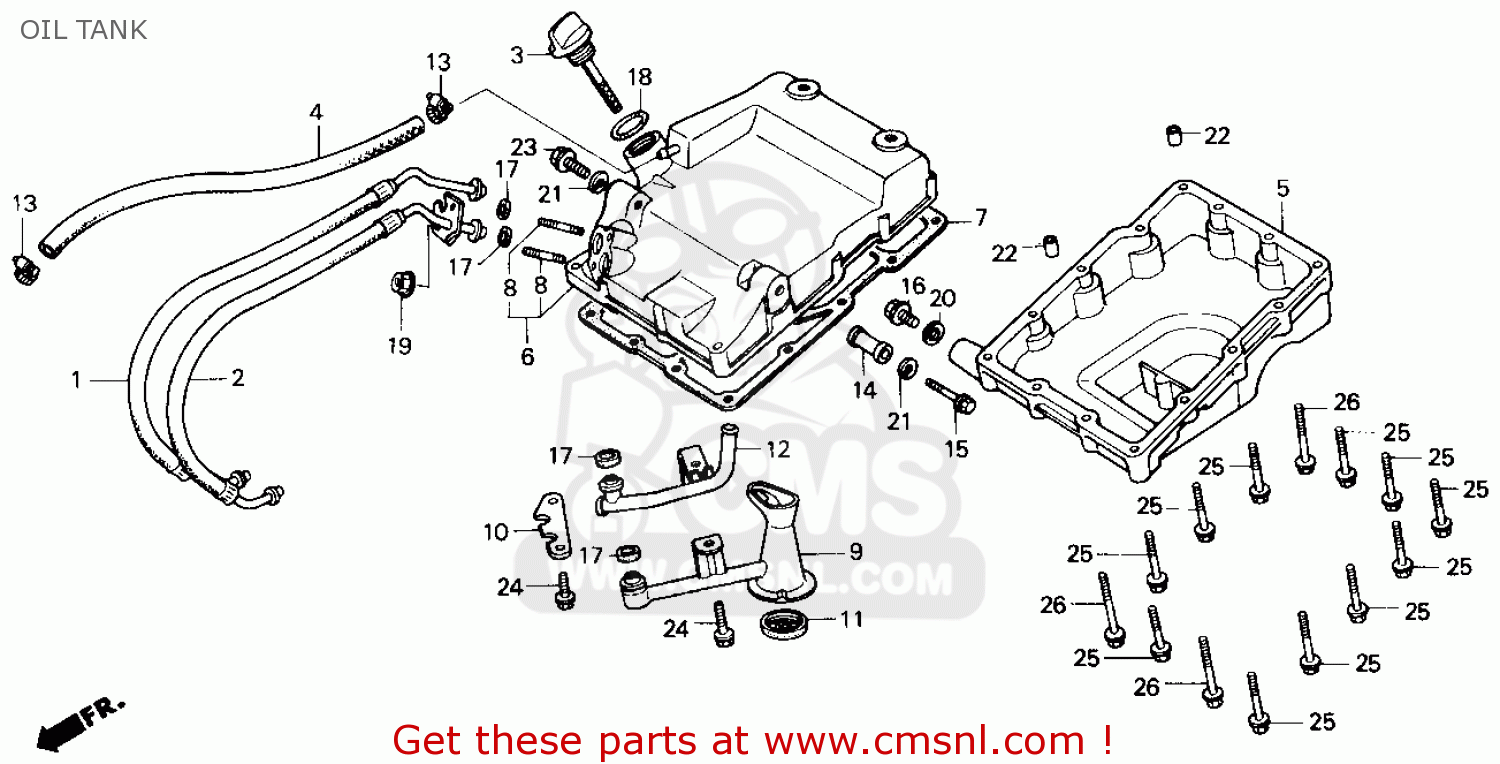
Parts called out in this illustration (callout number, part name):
1	HOSE A,OIL
2	HOSE B,OIL
3	GAUGE,OIL LEVEL
4	HOSE,BREATHER
5	TANK LOWER,OIL
6	TANK COMP,UPPER O
7	GASKET,OIL TANK
8	BOLT,STUD.6X25
9	BODY, OIL STRAINER
10	STOPPER,STRAINER
11	SCREEN,OIL FILTER
12	PIPE, OIL TANK
13	CLAMP,BREATHER HO
14	COLLAR,OIL TANK
15	BOLT,OIL TANK
16	BOLT,DRAIN PLUG
17	GASKET,RUBBER,10.
18	ORING 183
21	WASHER,SPG.,8MM
23	BOLT FLANGE,8X18
24	BOLT,FLANG,6X16
25	BOLT,FLANGE,6X32
26	BOLT,FLANGE,6X40
